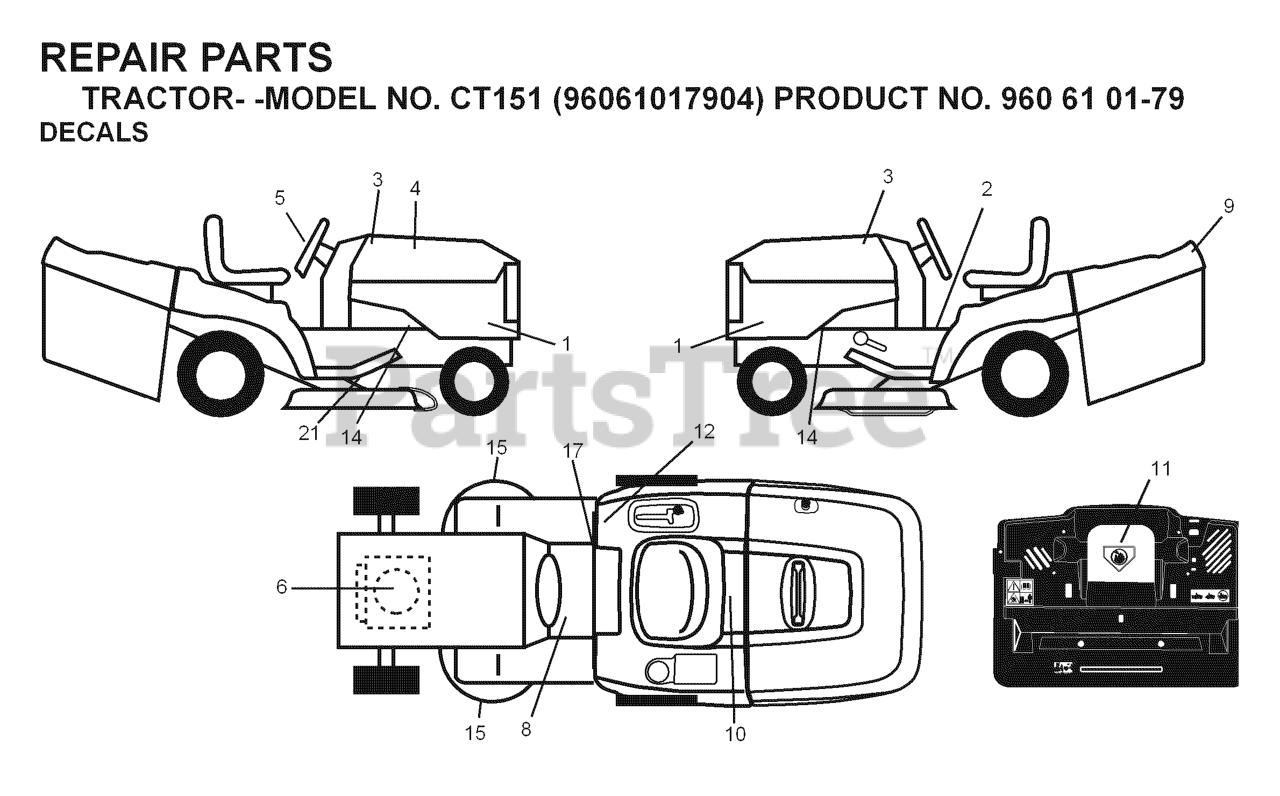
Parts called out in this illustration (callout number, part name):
2	LABEL
3	DECAL.HOOD.NAMELOGO.HUSQ
5	DECAL.WHEEL.STRG.LGN.H
6	DECAL
8	DECAL
9	DECAL.HOOD.NAMELOGO.HUSQ
10	DECAL BTRY SYMBOLS
11	DECAL.INTERNATIONL.CUTFINGER
12	Decal, Fender 100 DB/CE
17	DECAL PARK BRAKE
